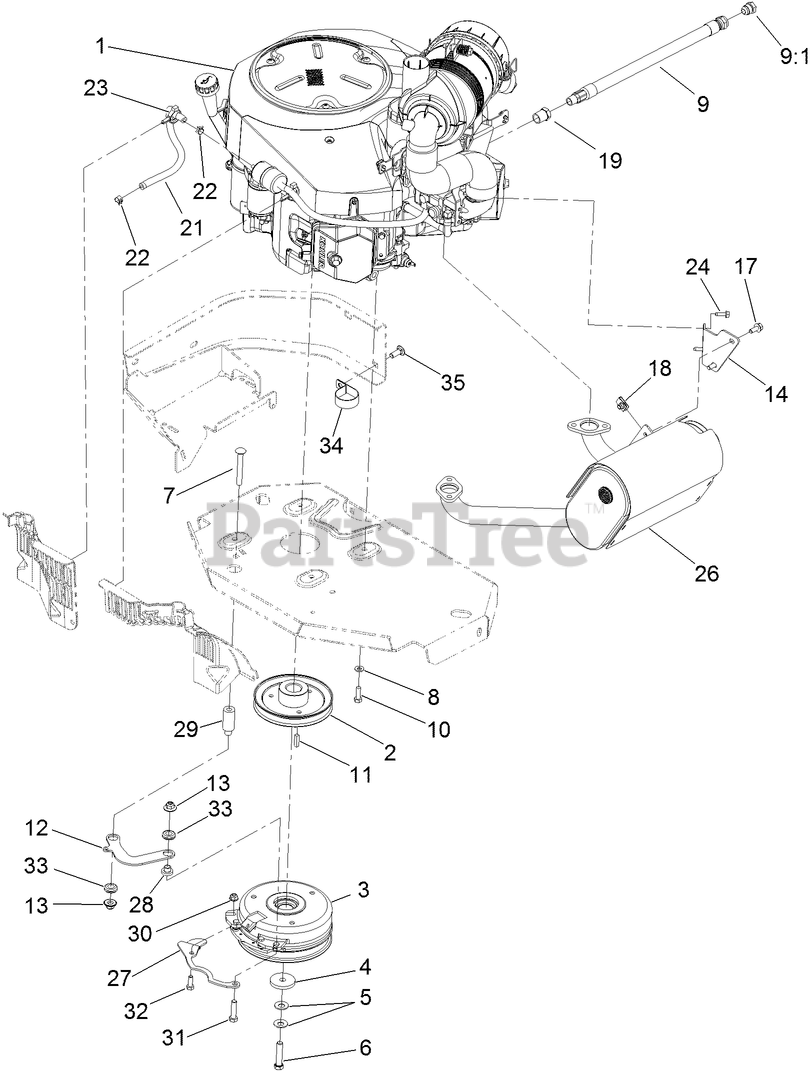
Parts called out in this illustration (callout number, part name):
2	SHEAVE
3	CLUTCH KIT
4	WASHER-CLUTCH
5	WASHER-SPRING
6	SCREW-HH W/LOCTITE
7	SCREW-CARR
8	WASHER-SPRING
9	OIL DRAIN HOSE ASM
10	SCREW-HH
12	LINK-ANCHOR, CLUTCH
13	NUT-FLANGE, NI
14	BRACKET-MUFFLER
17	SCREW-HHF
18	NUT-U
19	BUSHING
21	HOSE-FUEL
22	CLAMP-HOSE
23	CLAMP-HOSE
26	MUFFLER
27	BELT-GUIDE
28	SPACER
29	SPACER
30	NUT-HF, NI
31	SCREW-HH
32	SCREW-HH
33	GROMMET-RUBBER
34	CLAMP-R
35	SCREW-CARR
